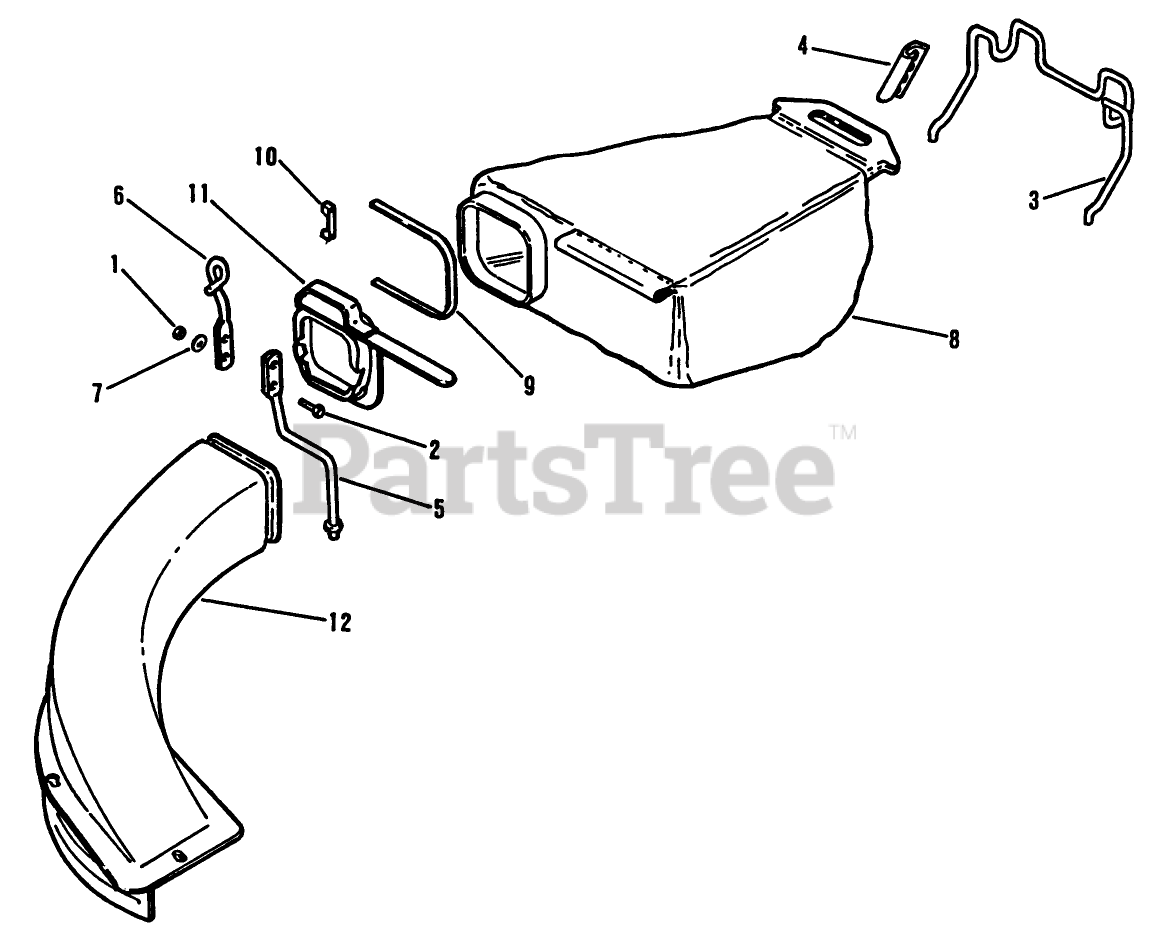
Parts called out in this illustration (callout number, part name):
1	LOCKNUT E
3	HANGER-WIRE
12	REAR CATCHR CHUTE
